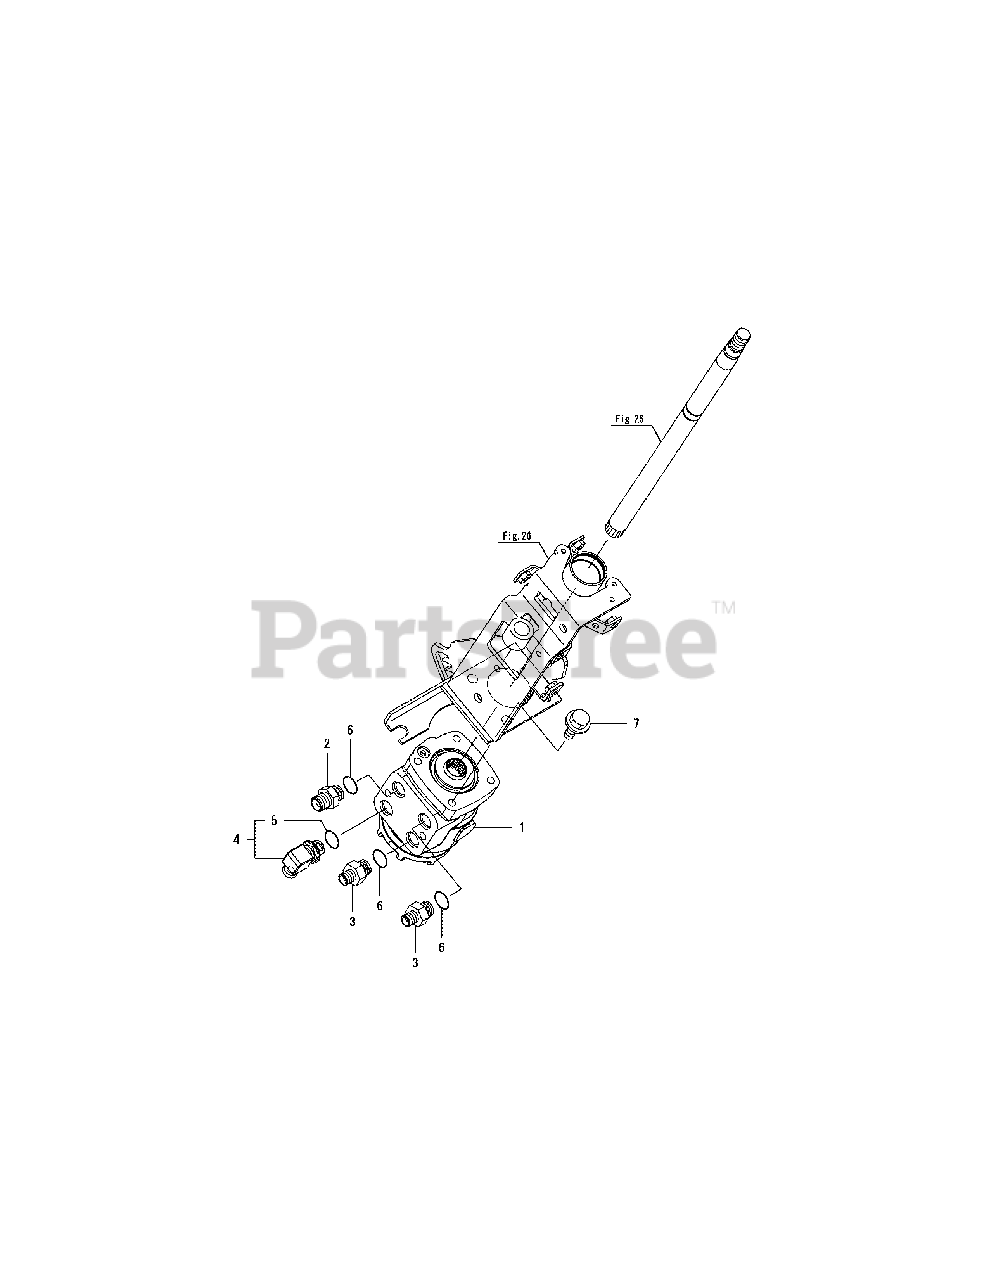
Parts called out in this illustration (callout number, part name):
4	JOINT 90-3/8 ASSY
5	O-RING 1B P-14.0
6	O-RING 1B P-14.0
7	BOLT M10X 20 PLATED
